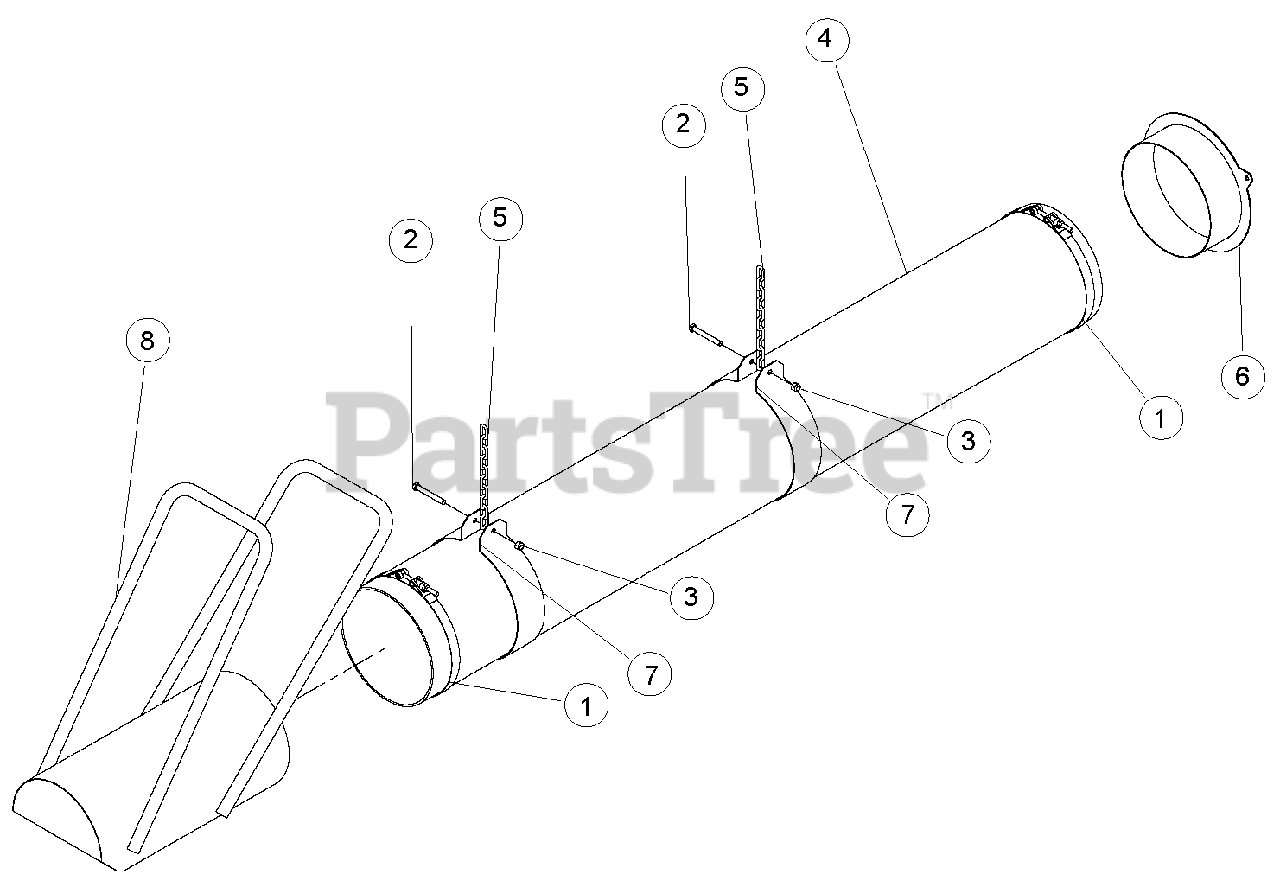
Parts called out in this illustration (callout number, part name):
1	CLAMP, 10.50 T-BOLT HOSE
2	BOLT, 3/8 NC X 3-1/2 HEX HD
3	NUT, 3/8" NYLOCK
4	HOSE, 10 IN X 12.5 FT INLET
5	CHAIN, HOSE SUPPORT
6	WELDMENT, INLET ADAPTER
7	WRAP, HOSE SUPPORT
8	WELDMENT, HOSE INLET
